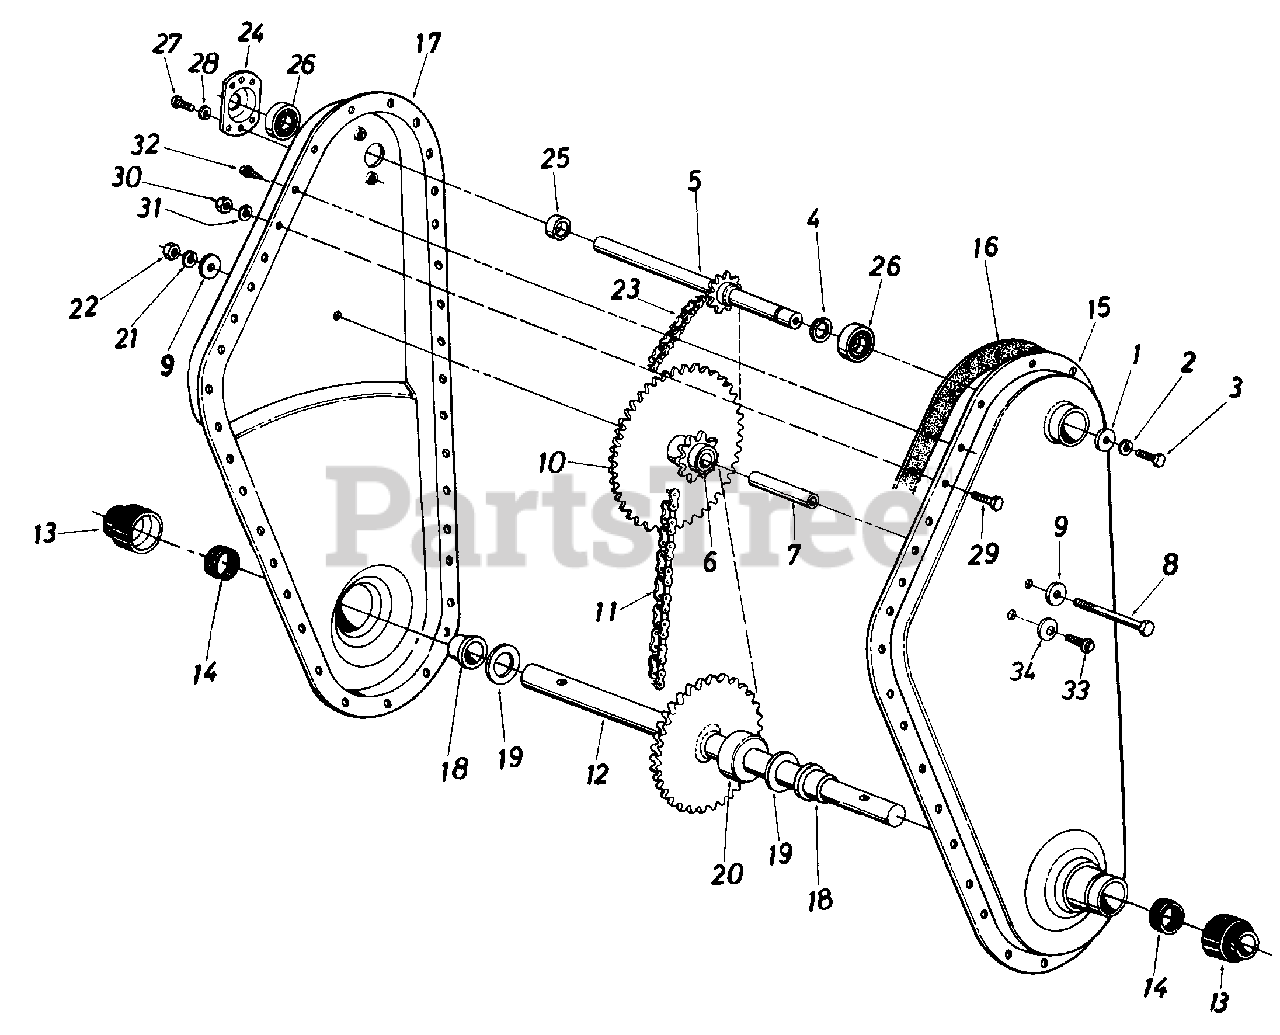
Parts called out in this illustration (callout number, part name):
1	Fl-Wash. 1/4" I.D. x .93" O.D.
2	L-Wash. 1/4" I.D.
3	Hex Bolt 1/4-28 x .62" Lg. w/Patch
4	External Snap Ring-5/8" Dia.
5	Input Shaft Ass'y.
6	Bearing 5/8" I.D. x 3/4" O.D. x 1.860" Lg.
7	Sprocket Hub Tubing 3/8" I.D. x 5/8" O.D. x 1.90
8	Hex Bolt 3/8-24 x 2.75" Lg.
9	Fl-Wash. 3/8" I.D. x 1.25"
10	sprocket Ass'y.
11	#50 Chain 5/8" Pitch x 46 Links Endless
12	Tine Shaft Ass'y.
13	Dust Cup
14	Seal Ring Single Lip
19	Fl-Thrust Wash. 1.0" I.D. x .03 Thk.
20	Step Spacer
21	L-Wash. 3/8" I.D."
22	Hex Nut 3/8-24 Thd.
23	#35 Chain 3/8" Pitch x 52 Links Endless
24	Bearing Housing 1.38" I.D.
25	Spacer
26	Ball Bearing .625" I.D. x 1.38" O.D. x .437
27	Hex Wash. SF-Tap Scr. 1/4-20 x .50" Lg.
28	L-Wash. 1/4" I.D.
29	Hex Bolt 5/16-18 x .75" Lg.
30	Hex Nut 5/16-18 Thd.
31	L-Wash. 5/16" I.D.
32	Hex Wash. SF-Tap Scr. 1/4-20 x .50" Lg.
33	Hex Wash. Hd. Tap Scr. 1/4-20 x .38" Lg.
34	Bell-Wash. .265" I.D. x .75"
